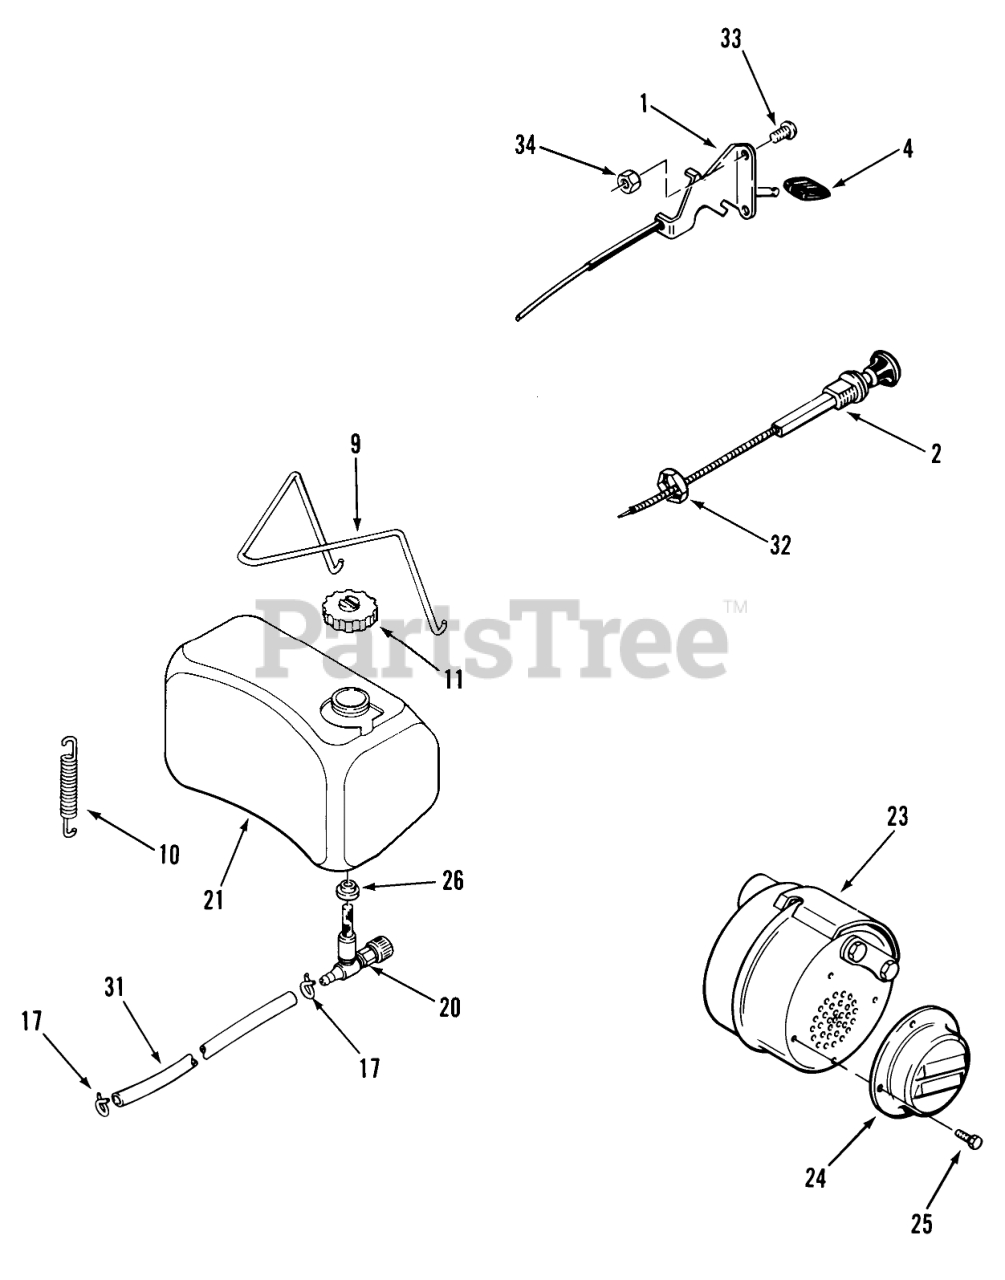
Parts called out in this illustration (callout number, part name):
1	CONTROL THROTTLE
2	Choke Control 216-5 Only
4	KNOB-THROTTLE
9	Hold Down Wire
10	SPRING-EXTENSION
11	CAP-GASOLINE
17	Clamp
20	VALVE-FUEL
21	Fuel Tank Assy
23	MUFFLER
24	DEFLECTOR MUFFLER
25	Hex HD Screw 8-32 x 3/8-Black-211-3, 211-5
26	BUSHING
31	Fuel Hose 14.5 in. (36.8 cm) B-115 Only
32	NUT-HEX PALNUT
33	Screw
34	Nut
